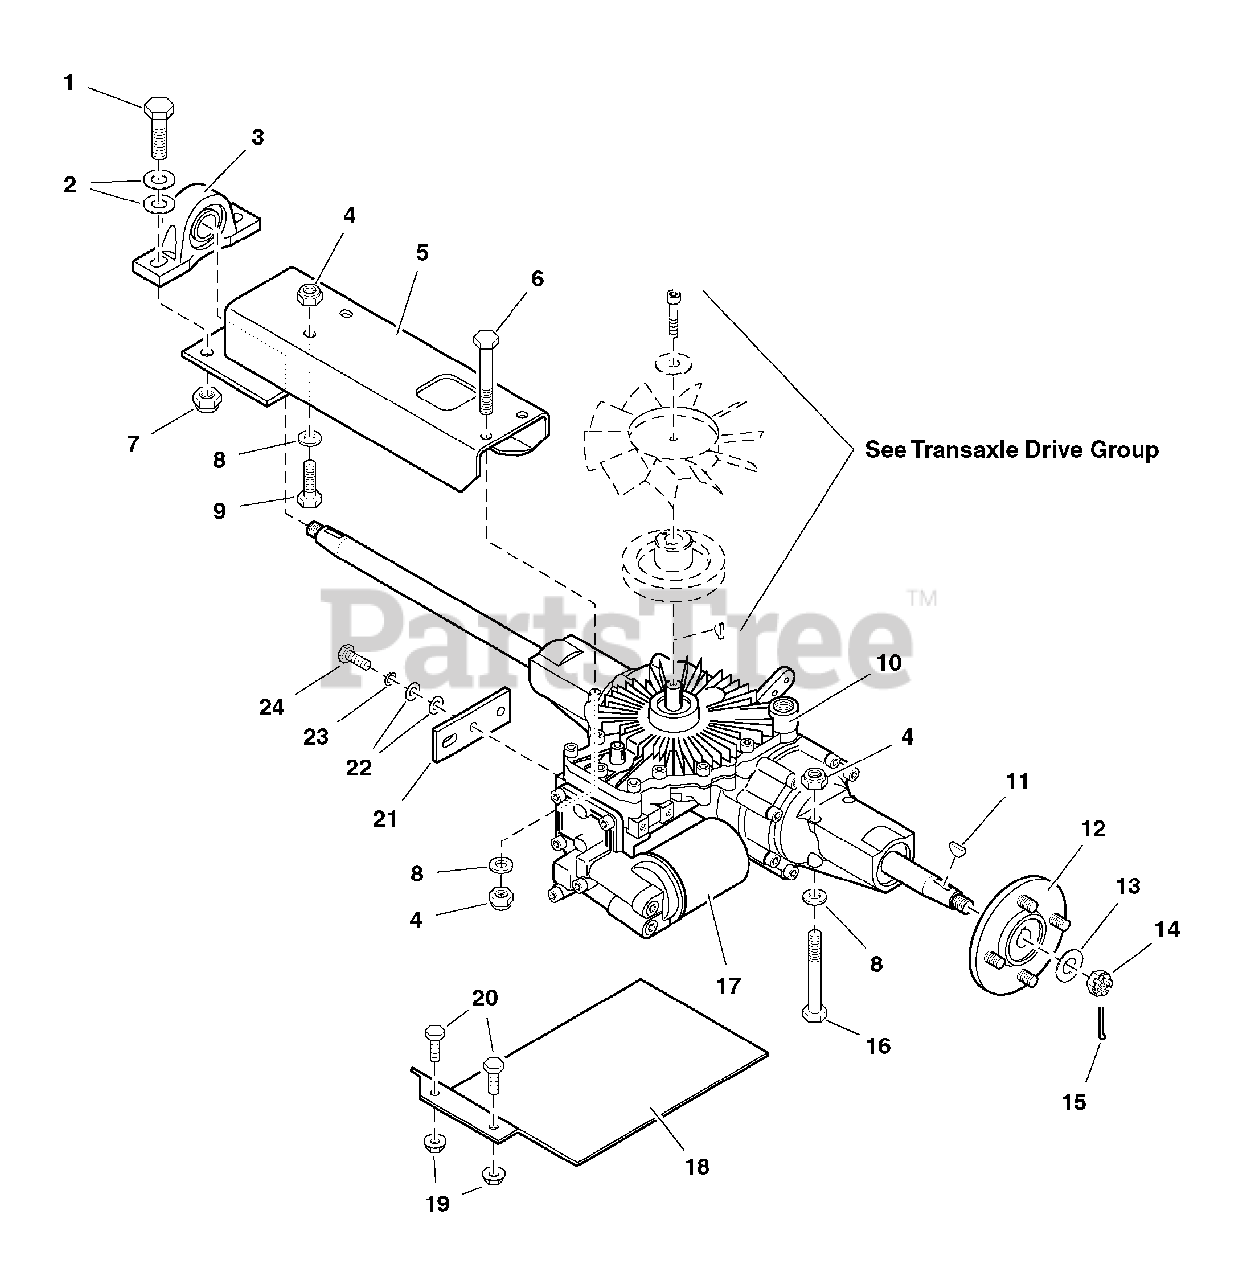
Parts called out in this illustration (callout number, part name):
1	CAPSCREW, Hex Hd, 7-16-20 x 1-3/4
2	WASHER, 7/16
3	BEARING, Pillow Block
4	NUT, Hex, Nylon Lock, 3/8-16
5	AXLE SUPPORT
6	CAPSCREW, Hex Hd, 3/8-16 x 3
7	NUT, Hex, Nylon Lock, 7/16-20
8	WASHER, 3/8, GD.9
9	CAPSCREW, Hex Hd, 3/8-16 x 1-1/4
10	HYDROSTATIC TRANSAXLE, complete (includes Ref 16,19 & 22)
11	KEY, Woodruff
12	HUB, 4-Bolt Tapered
13	WASHER, 3/4
14	NUT, Hex Slotted
16	CAPSCREW, Hex Hd, 3/8-16 x 3-1/2
19	NUT, Hex, Serrated Flange, 5/16-18
20	CAPSCREW, Hex Hd, 5/16-18 x 3/4
21	BRACKET, Transmission Support
22	WASHER, 5/16
23	WASHER, Lock, 5/16
24	CAPSCREW, Hex Hd, 5/16-18 x 1
